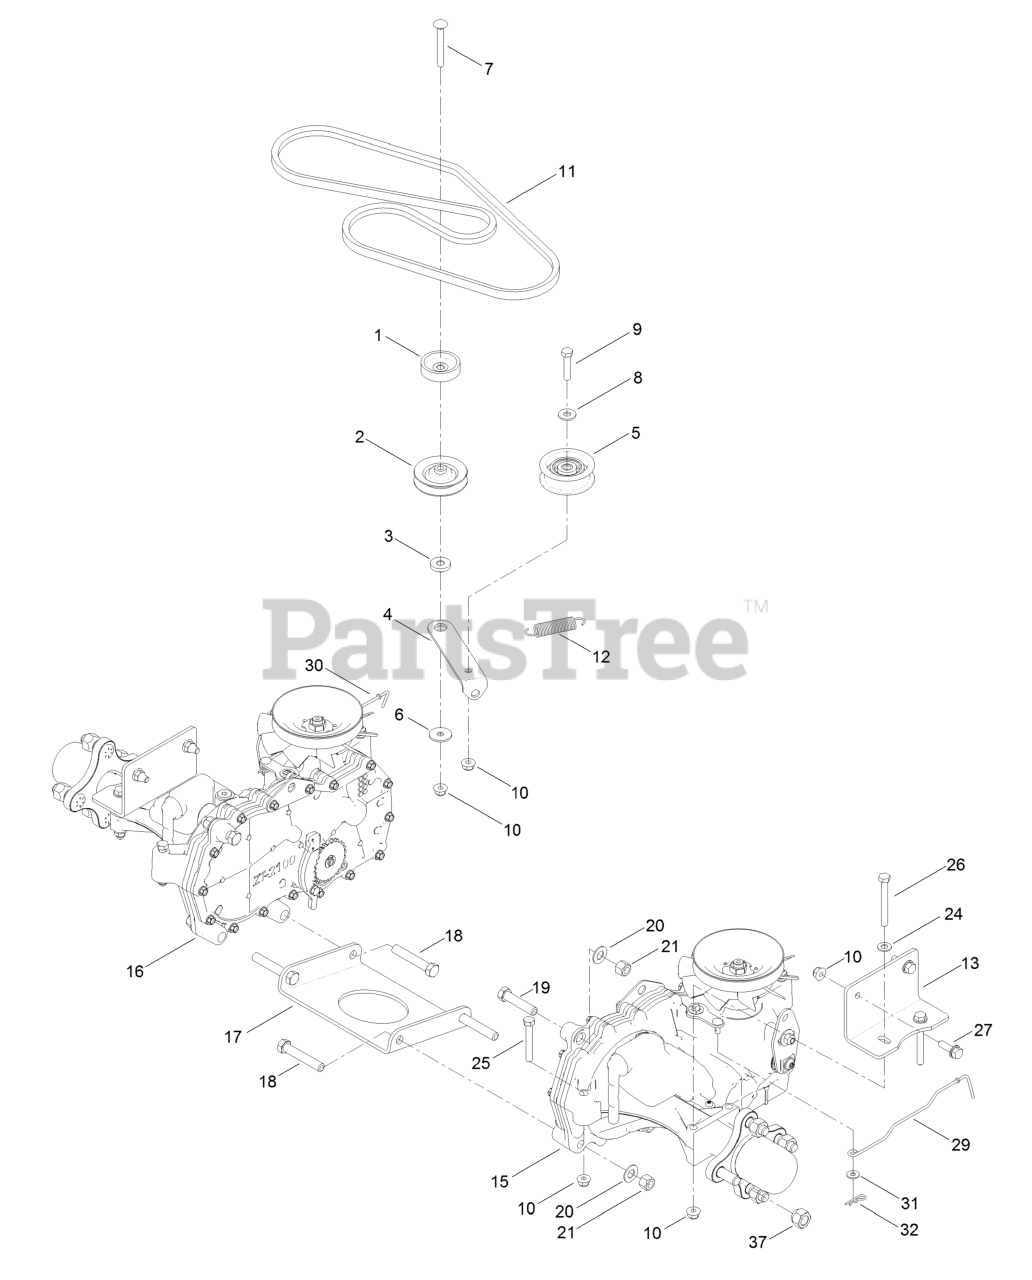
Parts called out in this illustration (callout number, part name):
2	Pulley-Idler
3	Spacer-Arm, Idler
4	Arm-Idler
5	Pulley-Idler
6	Washer-Pivot
7	Screw-CARR
8	Washer-Flat
9	Screw-HH
10	Nut-HF, NI
11	V-Belt
12	Spring-Return, Pedal
13	Mount-Hydro
15	LH Hydro Transaxle ASM
16	RH Hydro Transaxle ASM
17	Plate-Cross, Hydro
18	Screw-HH
19	Screw-HH
20	Washer-Flat
21	Nut-Lock, NI
24	Washer-Plain
25	Screw-HH
26	Screw-HH
27	Screw-HHF
29	Rod-Bypass, LH
30	Rod-Bypass, RH
32	Pin-Cotter
37	Nut-Lug
